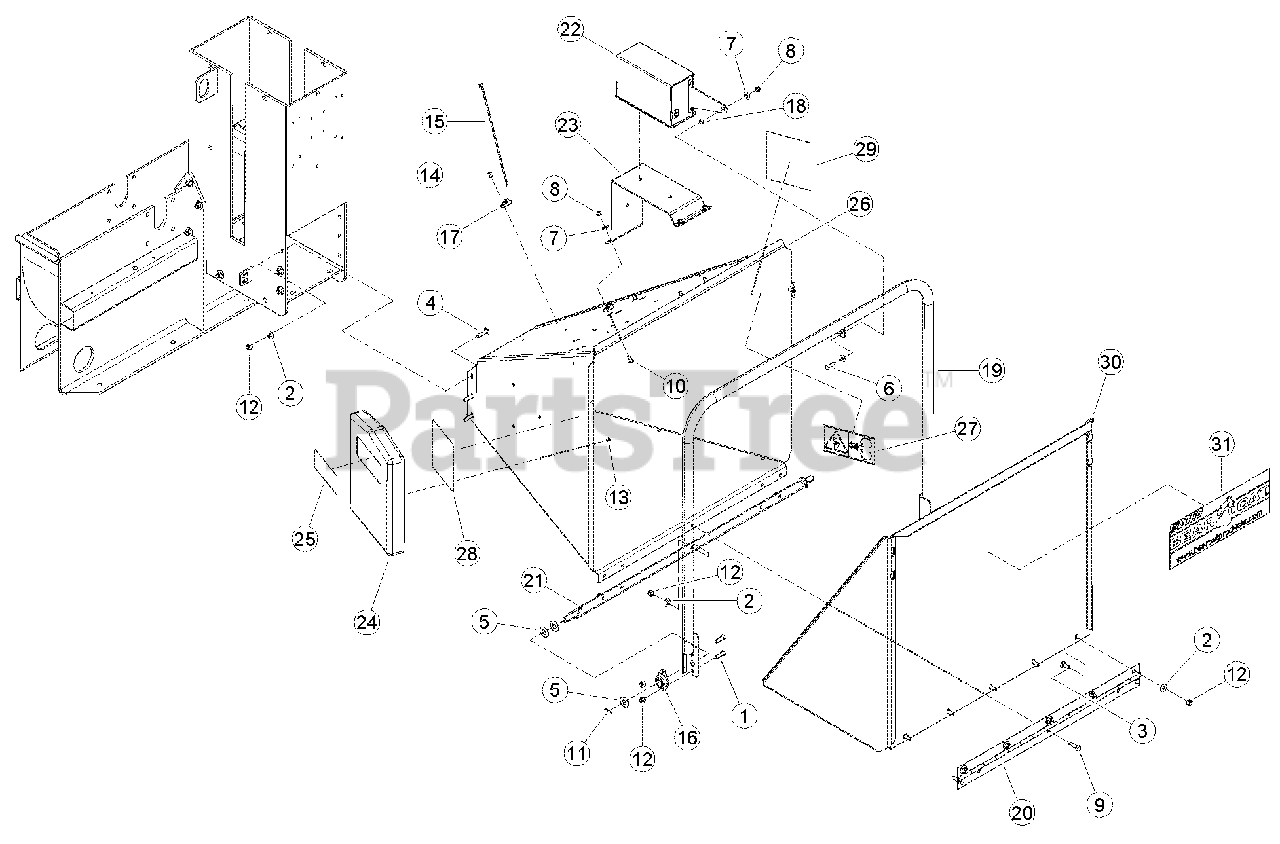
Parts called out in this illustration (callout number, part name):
1	BOLT, 3/8 X 1 HEX HD GR5 ZP
2	WASHER, 3/8 FLAT ZP
3	BOLT, 3/8 X 1 CRG GR5 ZP
4	BOLT, 3/8 X 1-1/2 CRG GR5 ZP
5	WASHER, 5/8 SAE FLAT ZP
6	BOLT, 5/16 X 1 HHCS GR5 NC ZP
7	WASHER, 5/16 FLAT ZP
8	NUT, 5/16 NE NYLOCK ZP
9	BOLT, 3/8 X 1-1/4 HEX HD GR5 ZP
10	BOLT, 5/16 X 3/4 CRG GR5 NC ZP
11	PIN, 1/8 X 1.00 ZP COTTER
12	NUT, 3/8 NE NYLOCK ZP
13	RIVET, AL BLIND 1/4 X 1/2 DOME HEAD
14	RIVET, AL BLIND 1/4 X 3/4 DOME HEAD
15	STRAP, 11 IN. BLACK TIE
16	BEARING, SIDE FLNG MOUNT 5/8"
17	CLAMP, CABLE MOUNT
18	SPACER, IDLER PIVOT
19	WELDMENT, CONTROL ARM
20	HINGE, EXTENSION TRAY
21	WELDMENT, CONTROL PIVOT
22	ASSEMBLY, SWITCH BOX
23	MOUNT, SWITCH BOX
24	ASSEMBLY, MANUAL CONTAINER, SERVICE PART
25	DECAL, MUTILINGUAL MANUAL
26	ASSEMBLY, BIG CHIPPER CHUTE, SERVICE PART
27	DECAL, BLADE DANGER ISO
28	DECAL, FEED POSITION
29	DECAL, FEED POSITION
30	ASSEMBLY, CHUTE EXTENSION TRAY, SERVICE PART
31	DECAL, BEARCAT WEB
